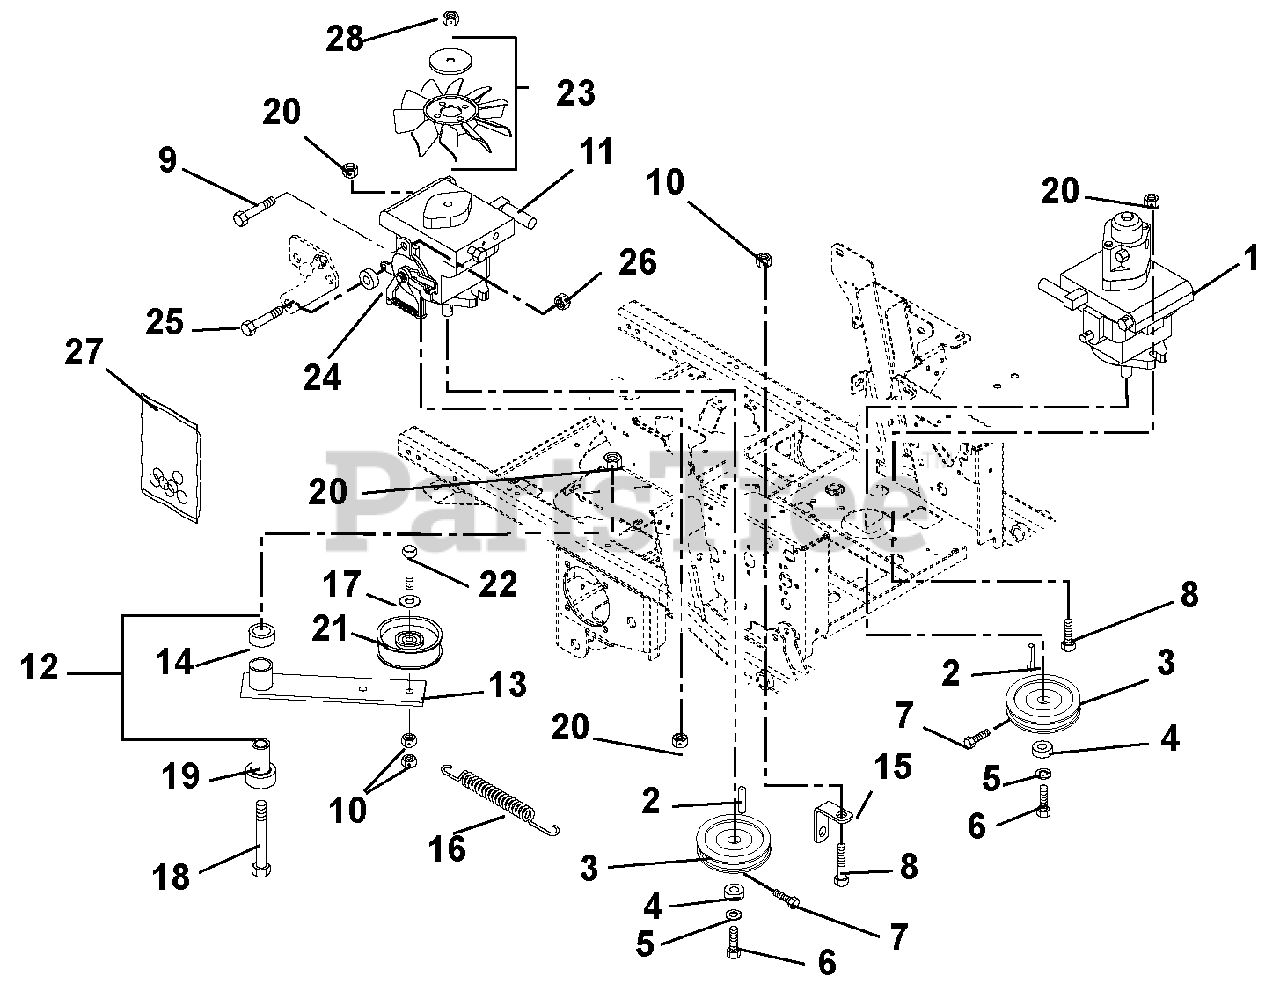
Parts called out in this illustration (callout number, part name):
1	Pump, Hydraulic with Auxiliary
2	Key, Square 5 x 5 x 30mm Plain
3	Sheave, Poly V .671 x 4.125
4	Washer, Flat Steel .281 x 1.000 x .063
5	Washer, Locking .25 x .062
6	Bolt, Hex M6 x 1.0 x 12 YZ EP30
7	Screw, Socket Head .25-20 x .50 YZ EP80
8	Bolt, Hex .50-13 x 1.50 Grade 5
9	Bolt, Hex .31-18 x .75 Grade 5
10	Nut, Locking Top Flange .38-16
11	Pump, Hydraulic BDP – 21 with Thru Fan (page 19)
12	Assembly, Idler Arm Guard Drive (Includes 13 & 14)
13	Weldment, Idler Arm Ground Drive
14	Bushing, 1.00 x 1.125 x 1.936
15	Anchor, Spring Idler
16	Spring, Tension
17	Washer, Flat Steel .39 x .75 x.125
18	Bolt, Hex .50-13 x 3.50 Grade 5
19	Bearing, Pedestal
20	Nut, Locking Top Flange .50-13
21	Idler, Flat 4.00 x .38
22	Bolt, Hex .38-16 x 2.25 Grade 5
23	Fan, Cooling
24	Spacer .318 x .43 x .375
25	Bolt, Hex .31-18 x 1.25 Grade 5
26	Nut, Locking Top Flange .31-18
27	Kit, Pump Seal (BDP – 21A) (One kit required for each pump)
28	Nut, Center Lock .31-24
